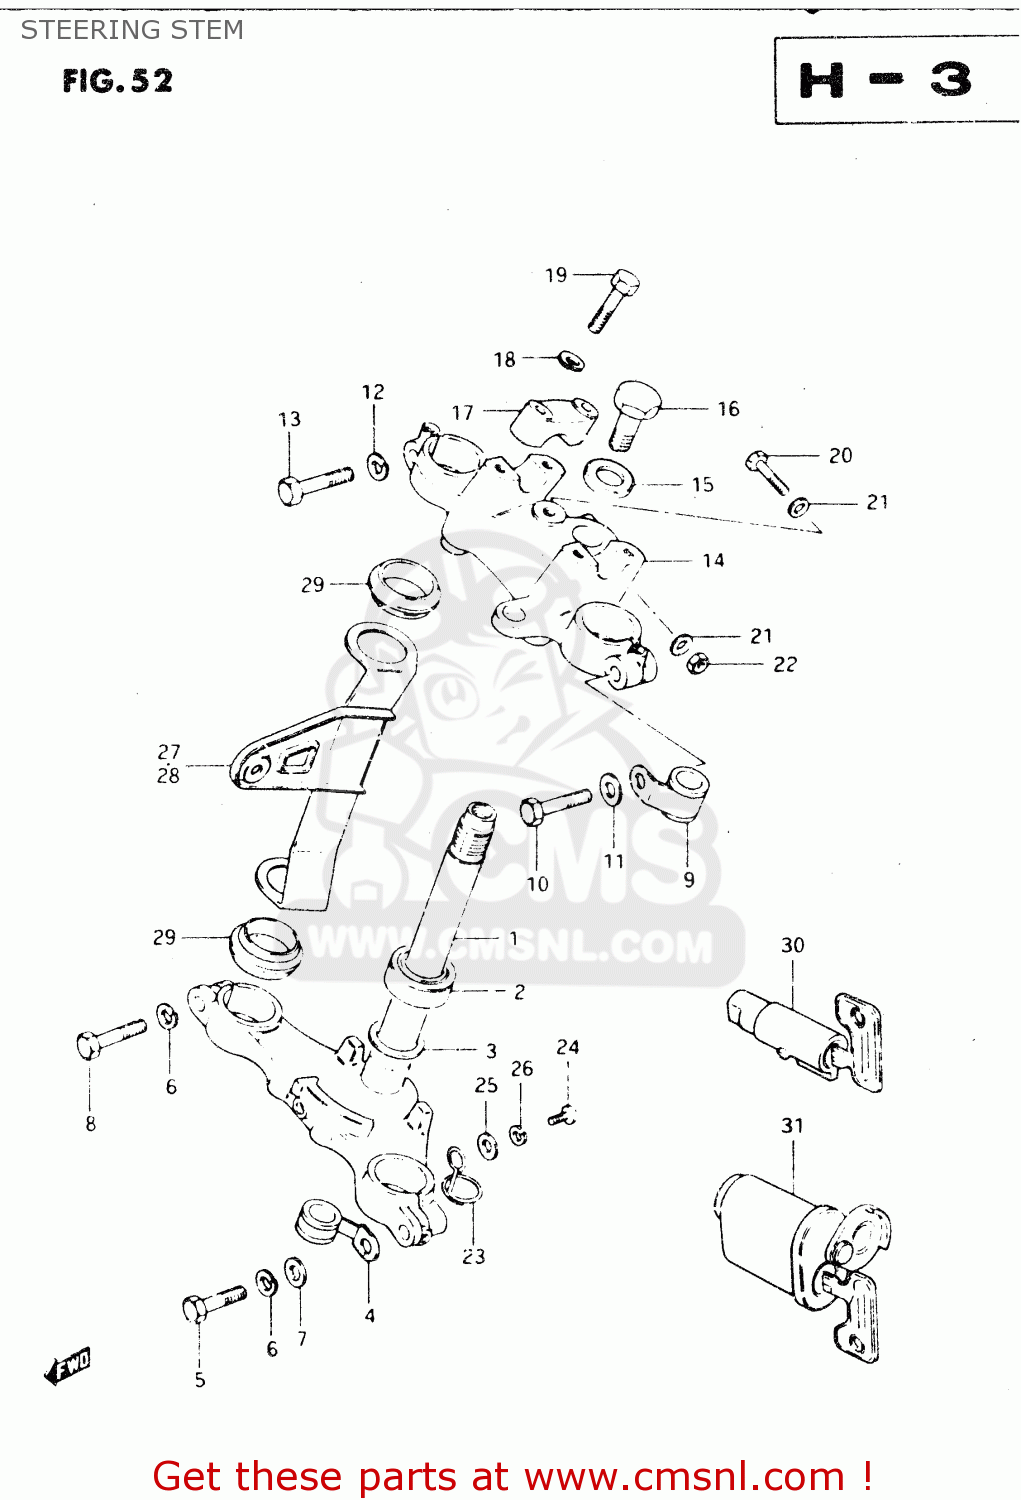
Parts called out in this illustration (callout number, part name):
1	STEM,STEERING
2	BEARING
3	WASHER,THRUST
4	CLIP
5	BOLT 12X45
6	WASHER,LOCK 12
7	WASHER
8	BOLT
9	CLIP
10	BOLT 10X40
11	WASHER
12	LOCK WASHER
13	BOLT 10X40
14	HEAD,STEERING STEM
15	WASHER
16	BOLT,STEERING STEM HEAD
17	HOLDER,HANDLEBAR
18	LOCK WASHER
19	BOLT
20	BOLT 8X50
21	WASHER
22	NUT
23	CLIP
24	SCREW
25	WASHER
26	LOCK WASHER
27	BRACKET,HEADLAMP,RIGHT
28	BRACKET,HEADLAMP,LEFT
29	GASKET
30	LOCK ASSY,STEERING(NEIMAN)
